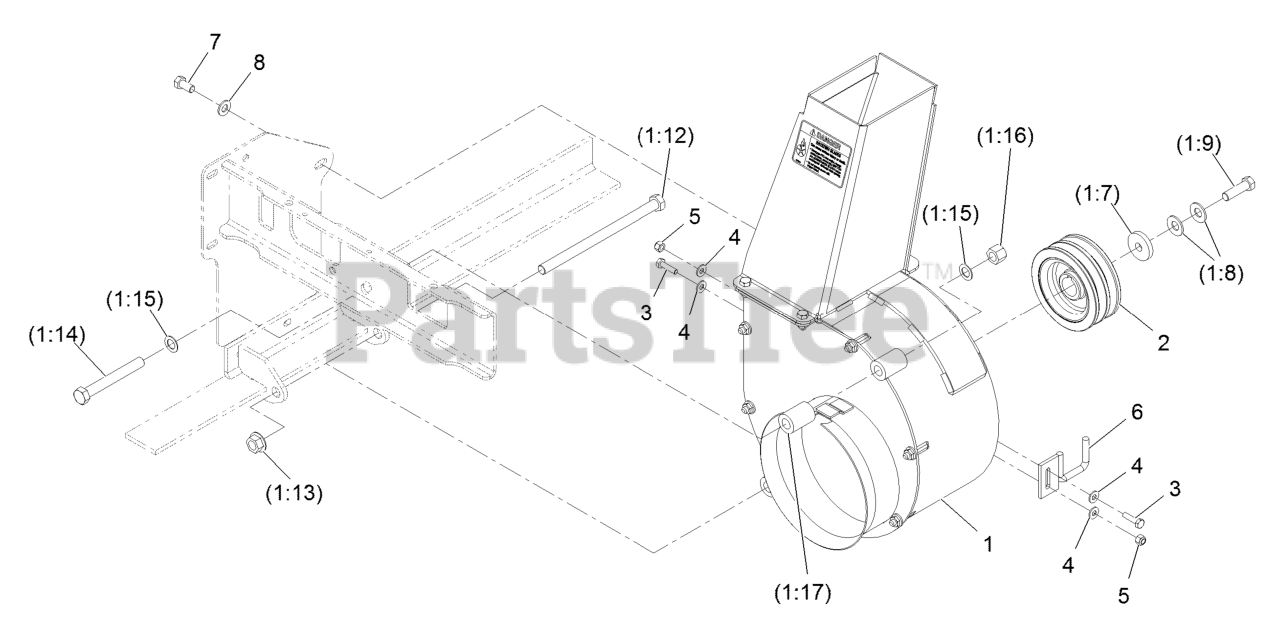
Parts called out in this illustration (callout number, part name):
1	BLOWER ASM
3	SCREW-HH
4	WASHER-FLAT
5	NUT-LOCK, NI
7	SCREW-HH
8	WASHER-FLAT
